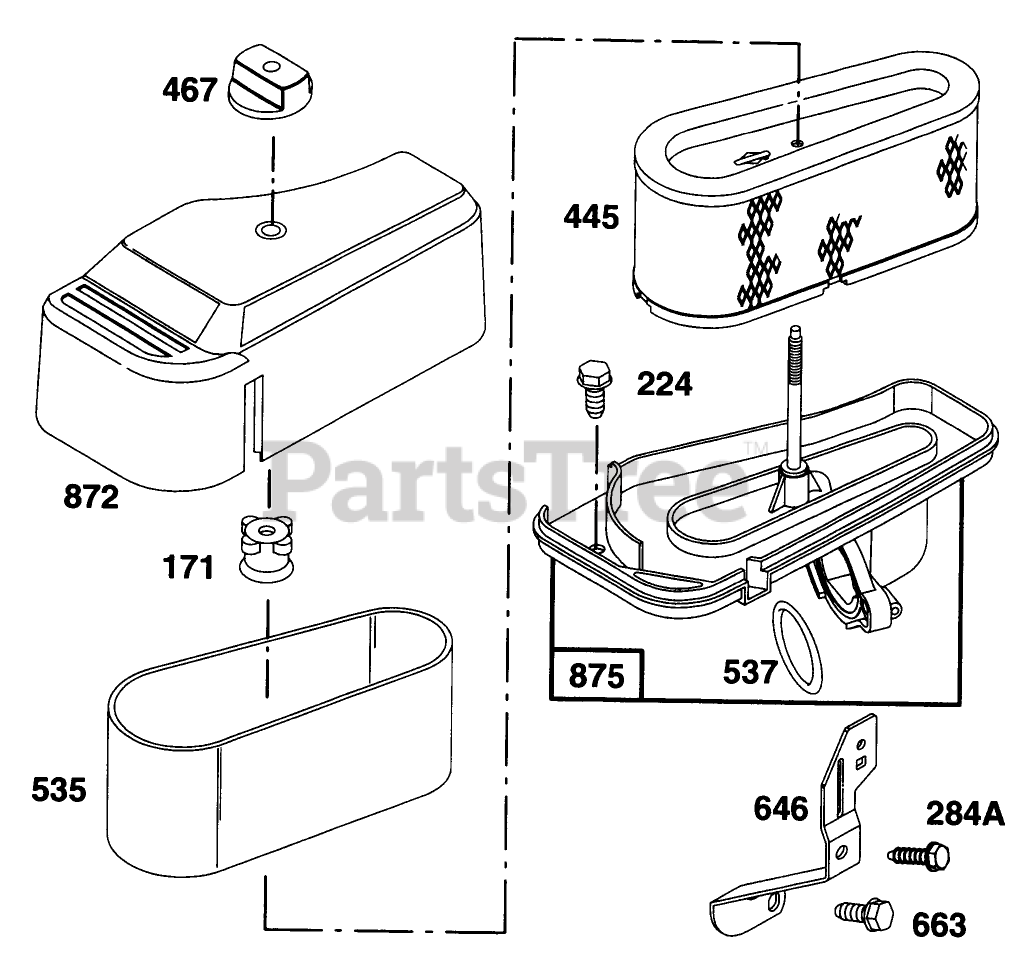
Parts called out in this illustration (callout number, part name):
224	Screw-Sem
284A	Screw
445	Filter-Air
535	Filter-Air
537	O-Ring
646	Brace-Air Cleaner
663	Screw
872	Cover-Air Cleaner
875	Body-Air Cleaner
